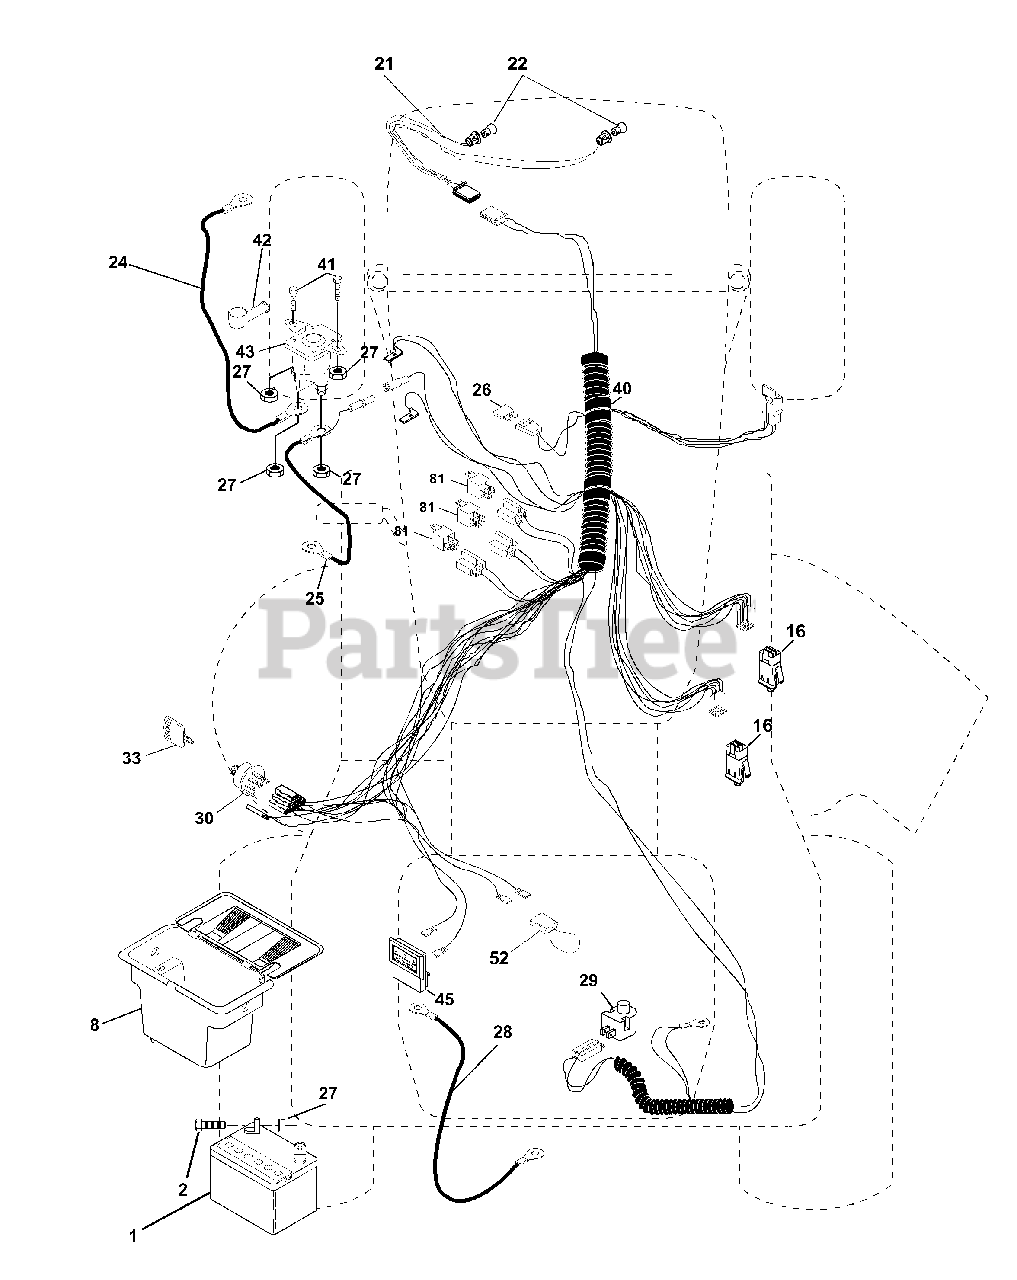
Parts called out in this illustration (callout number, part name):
1	Battery
2	Bolt Hex Hd 1/4-20unc X 3/4
8	Case Battery Mech Hinge
16	Switch Interlock
21	Harness Socket Light
22	Bulb, Light # 1156
24	Cable Battery
25	Cable Battery 6 Ga Red w/16 wire
26	Fuse Amp
27	Nut Keps Hex 1/4-20 Unc
28	Cable Ground 6ga 12 black
29	Switch Plunger
30	Switch Ign
33	Key Ign Molded Generic
40	Harness Ign
41	Bolt Fin Hex 1/4-20uncx 1/2
42	Cover Terminal Red
45	Ammeter Rectangular
52	Protection Loop
81	Relay Asm.
